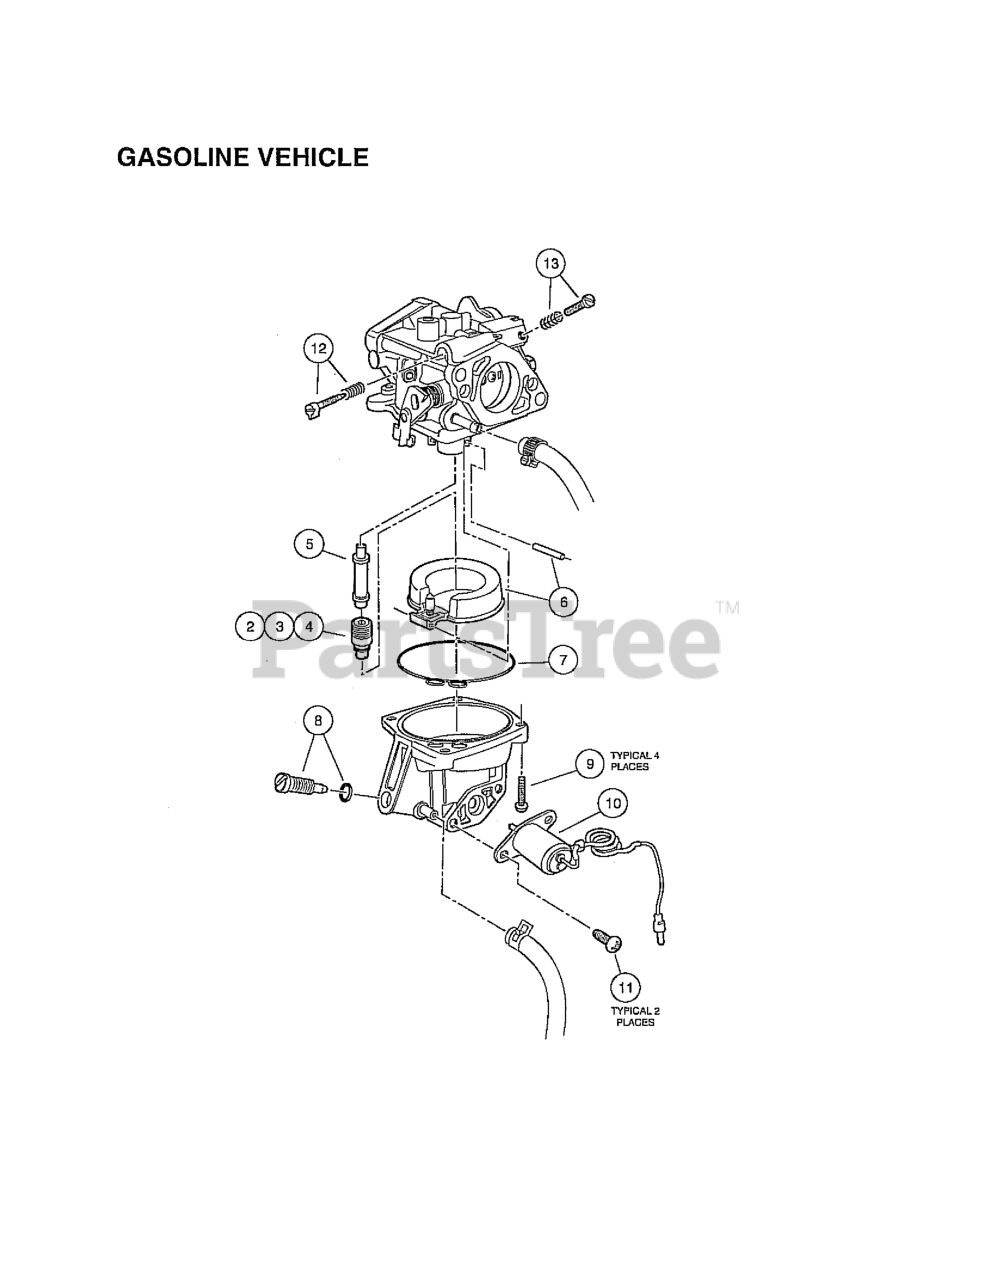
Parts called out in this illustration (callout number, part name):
1	CARBURETOR ASSY, BF22G A
2	Jet, GX620, #102 (8000 ft. and higher (2438 m and higher))
3	Jet, GX620, #105 (5000-8000 ft. (1524-2438 m))
4	Jet, GX620, #108 (0-5000 ft. (0-1524 m))
5	NOZZLE, MAIN
7	GASKET SET
8	SCREW SET, DRAIN
9	SCREW-WASHER, M4 X 14
10	VALVE ASSY., SOLENOID
11	SCREW-WASHER, M5 X 12
12	SCREW-SET-LEFT
13	SCREW SET, RIGHT
